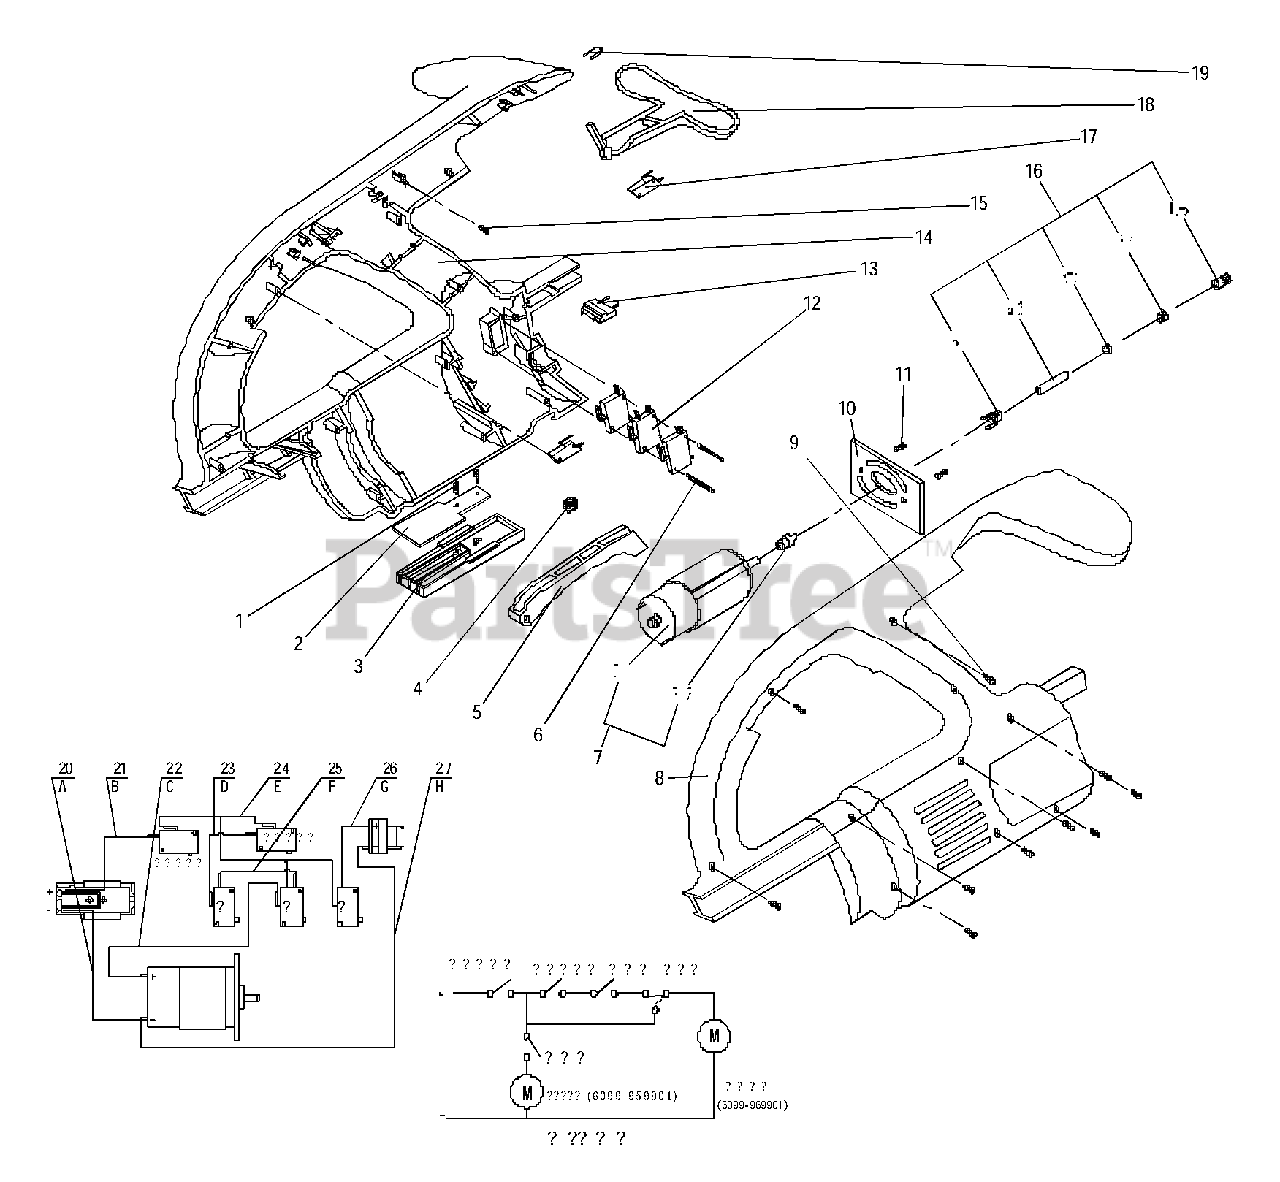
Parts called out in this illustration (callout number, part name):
2	PRESSURE PLATE
3	SOCKET, MAIN BODY
5	BUTTON, AFTER
7	MOTOR ASS'Y
8	HOUSING (L)
10	MOTOR PLATE
13	TERMINAL HOLDER
14	HOUSING (R)
16	SHAFT ASS'Y
16	SHAFT SLEEVE
16	CONNECTION SHAFT
18	BUTTON, FRONT
19	SPRING CLIP
